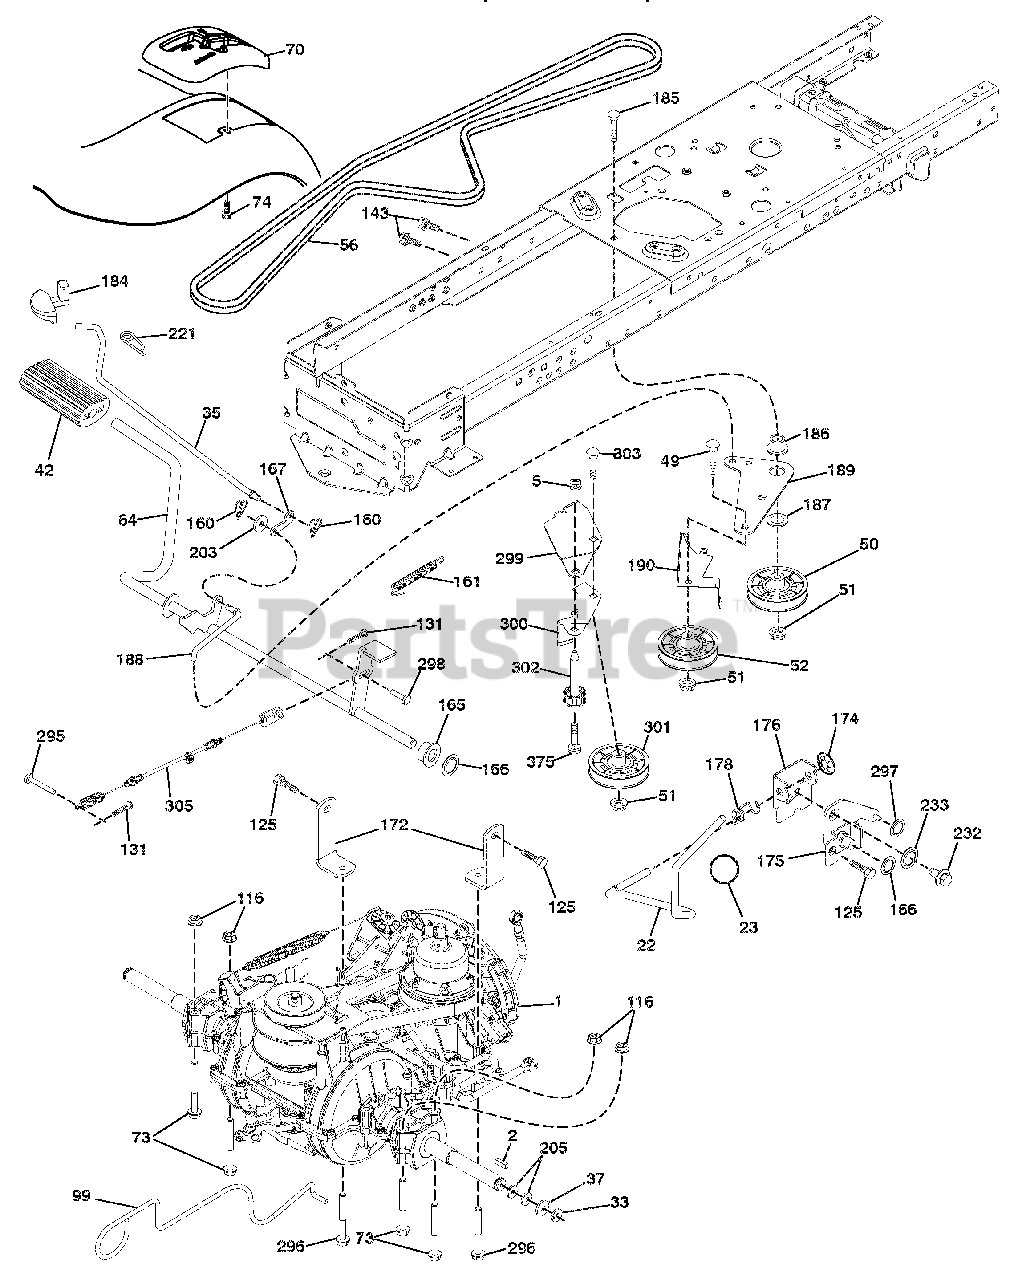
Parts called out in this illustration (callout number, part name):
1	TRANSAXLE, 415663
2	KEY.SQUARE.2.0 X .1845/.1865
5	Nut, Hex, Crownlock 3/8-16
22	Rod Shift
33	E-RING.#5133-75
35	ROD.BRAKE.PARKING.LT.TEX
37	WASHER.25/32 X 1 1/4 X 16 GA.
42	COVER.PEDAL.BLK.ROUND
49	BOLT.RDHD.3/8-16UNCX1-3/4.GR5
50	IDLER.FLAT.910"OFFSET
51	Nut, Hex, Flangelock 3/8-16
52	IDLER.V-GROOVE.910"OFFSET
56	BELT.DRIVE.100.97"
64	SHAFT ASM.PEDAL.BRAKE CONTROL
70	Console
73	BOLT.HEX.FLGHD.5/16-18.GR.5
74	SCREW.HEX.WSH.HI-LO.1/4X1/2UNC
99	Rod Bypass
116	Nut, Lock Hex Flange 5/16-18 u
125	SCREW.5/16-18X3/4.SMGML.TAP/BL
131	Pin Cotter 3/32/ x 3/4
143	SCREW.THDROL.5/16-18 X 1/2TYTT
160	RETAINER.CLIP(M).DIA.290
161	SPRING.RETURN.CLUTCH.6.75
165	BUSHING.SHAFT.BRAKE.HAND CONTR
166	Nut Push .625
167	LATCH.BRAKE.PARKING
172	Strap Torque LH/RH
174	NUT.PUSH..500
175	Shaft Asm Shift
176	ARM.CLEVIS.ROD.SHIFT
178	SPRING.SHIFT.GT.2006
184	HANDLE.PARKING BRAKE.LTTEX.505
185	BOLT.RDHD.3/8-16UNC X2-3/4 GR5
186	SPACER.RETAINER
187	WASHER.13/32 X 2 X 10 GA.
188	LINK.CLUTCH.GROUND DRIVE
189	BELLCRANK.GROUNDRIVE.NSTG/NSTL
190	KEEPER.BELLCRANK.DRIVE.GROUND
203	Washer 11/32 x 11/16 x 16 Ga.
205	WASHER.25/32 X 1-5/8 X 16GA.
221	RETAINER.SPRING.CLIP.HANDLE
232	BOLT.FIN HEX.7/16-14X1 GR5
233	WASHER.SERRATED
295	Pin Clevis 183 OD X 1.260 Long
296	Screw Thdrol 5/16-18 x 3
297	Nut Push 1/4
298	Pin Clevis Cbl. Brk. Variator
299	Bracket Mount Idler
300	Keeper Idler Rear
301	Pulley Idler V-Groove
302	Pulley Idler Flat 2.0 OD
303	Bolt Rdhd Sgnk 3/8-16 x 2-1/4
305	Cable Brake Variator
375	BOLT.HEX.HS.3/8-16.UNCX2-1/4
